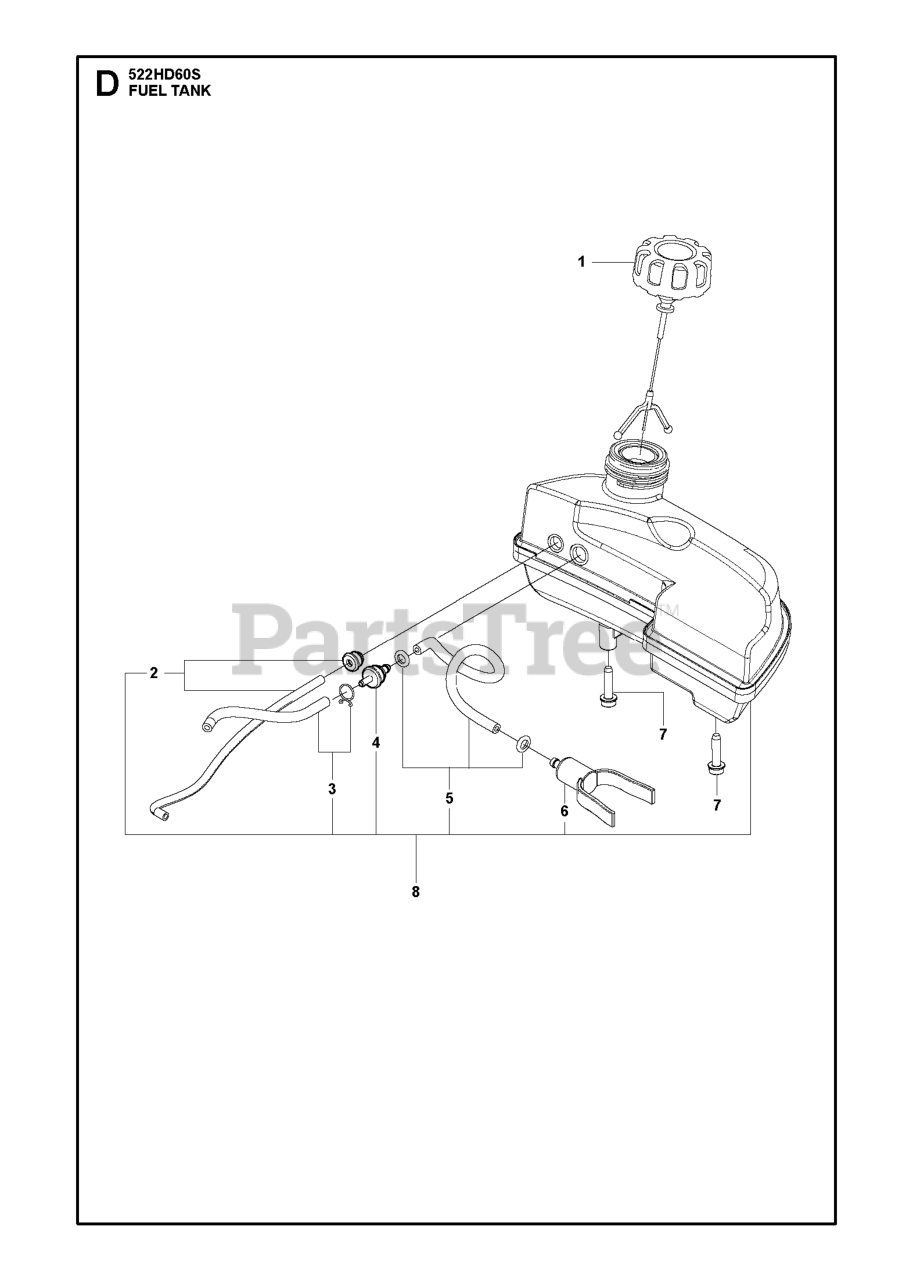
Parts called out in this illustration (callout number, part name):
2	HOSE KIT 522
3	HOSE KIT 522
3	HOSE KIT
4	HOSE NIPPLE
5	HOSE KIT 522
6	FUEL FILTER
8	FUEL TANK KIT 522
